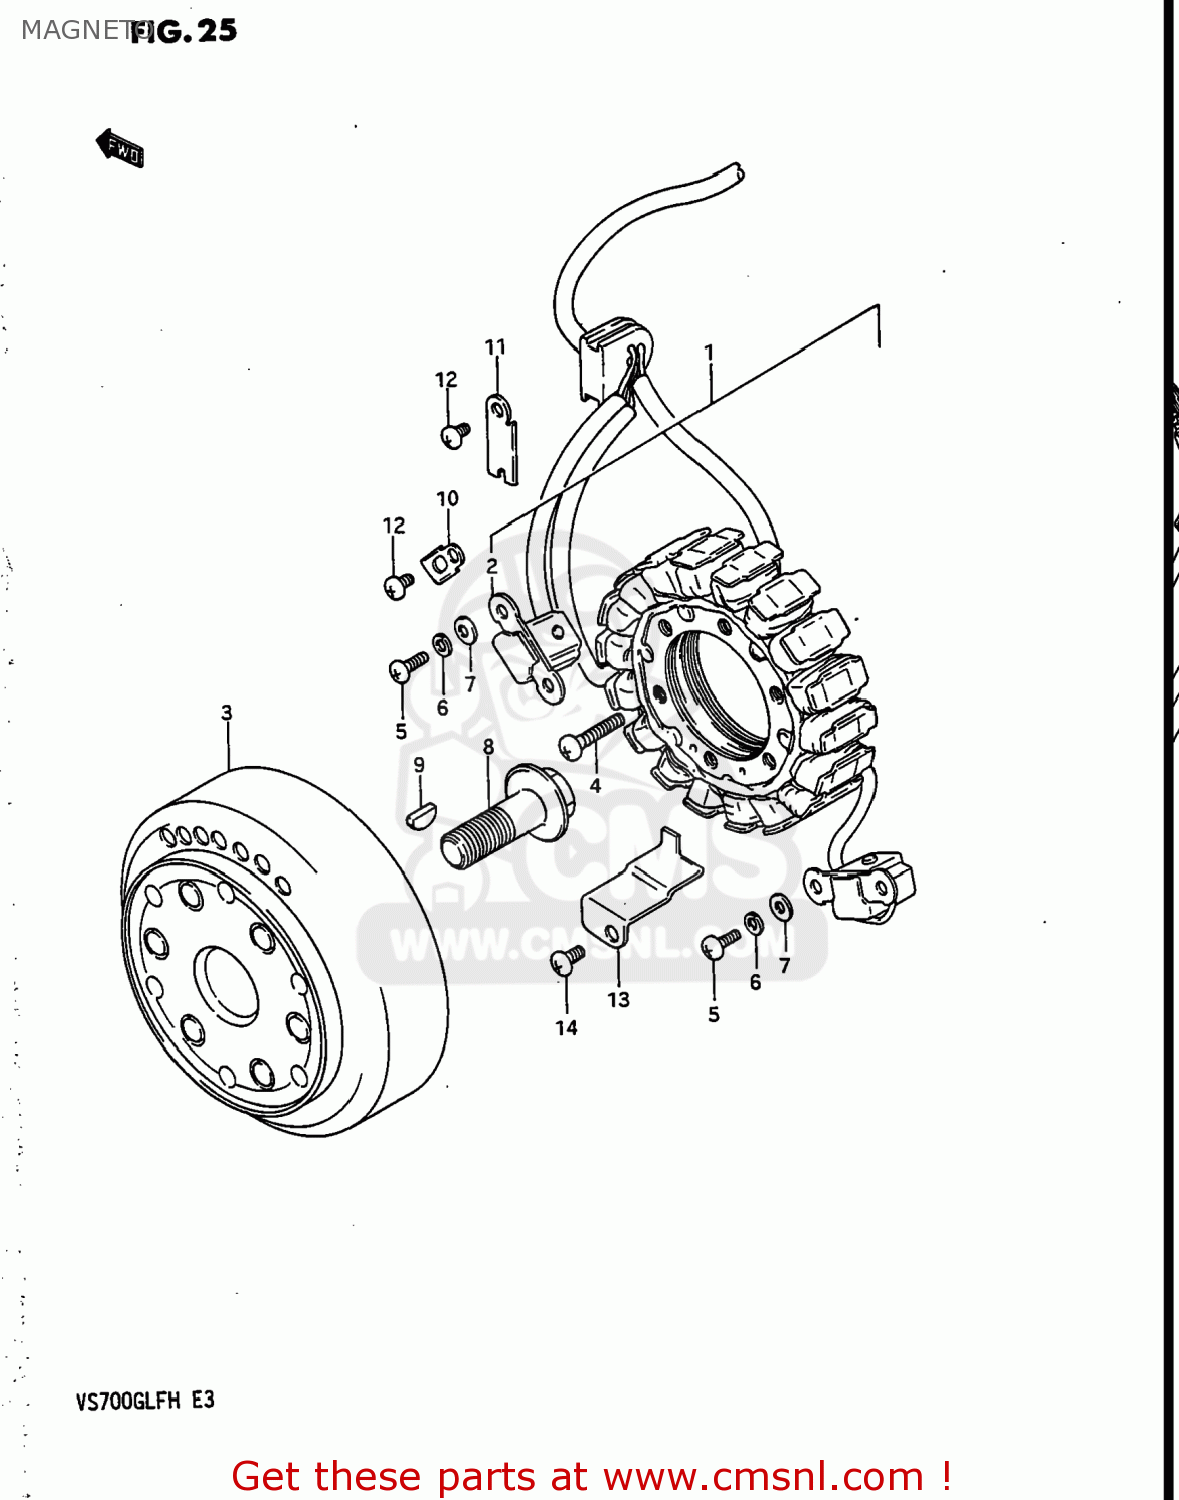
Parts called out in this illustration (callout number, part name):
1	STATOR ASSEMBLY
2	COIL ASSEMBLY,PICK-UP
3	ROTOR
4	SCREW 6X30
5	SCREW
6	WASHER
7	LOCK WASHER
8	BOLT(14X43)
9	KEY 4MM
10	CLAMP,GENERATOR LEAD WIRE
11	CLAMP NO.1,MAGNETO READ WIRE
12	SCREW
13	CLAMP,MAGNETO LEAD WIRE
14	SCREW
